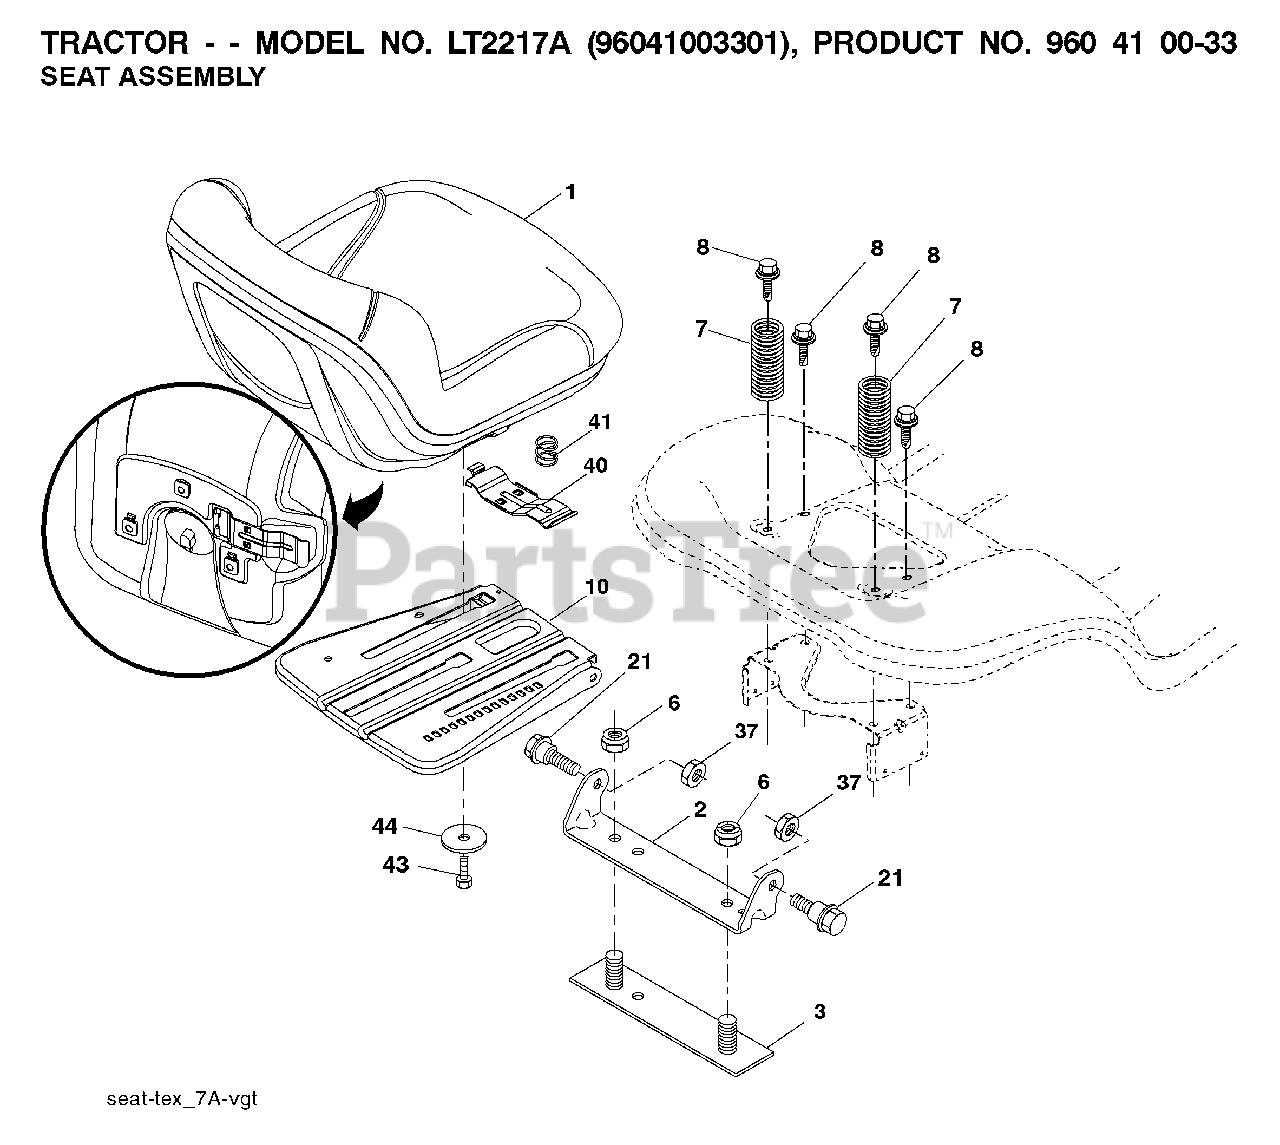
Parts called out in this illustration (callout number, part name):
1	SEAT.TG130.BLACK.NO/LOGO.
2	BRKT.PIVOT.FENDER
6	NUT
7	SPRING COMPRESSION
8	BOLT, 5/16-18 X 1 3/4
10	PAN.ASM.SEAT.3PT
21	BOLT.SHOULDER.5/16-18
37	NUT.71038.31-18.HEX.NYLOCK
40	HANDLE.SLIDE.SEAT.TEX.BLACK
41	SPRING.LATCH.SEAT.TEX
44	WASHER 13/32 X 2-3/8 X 12GA
